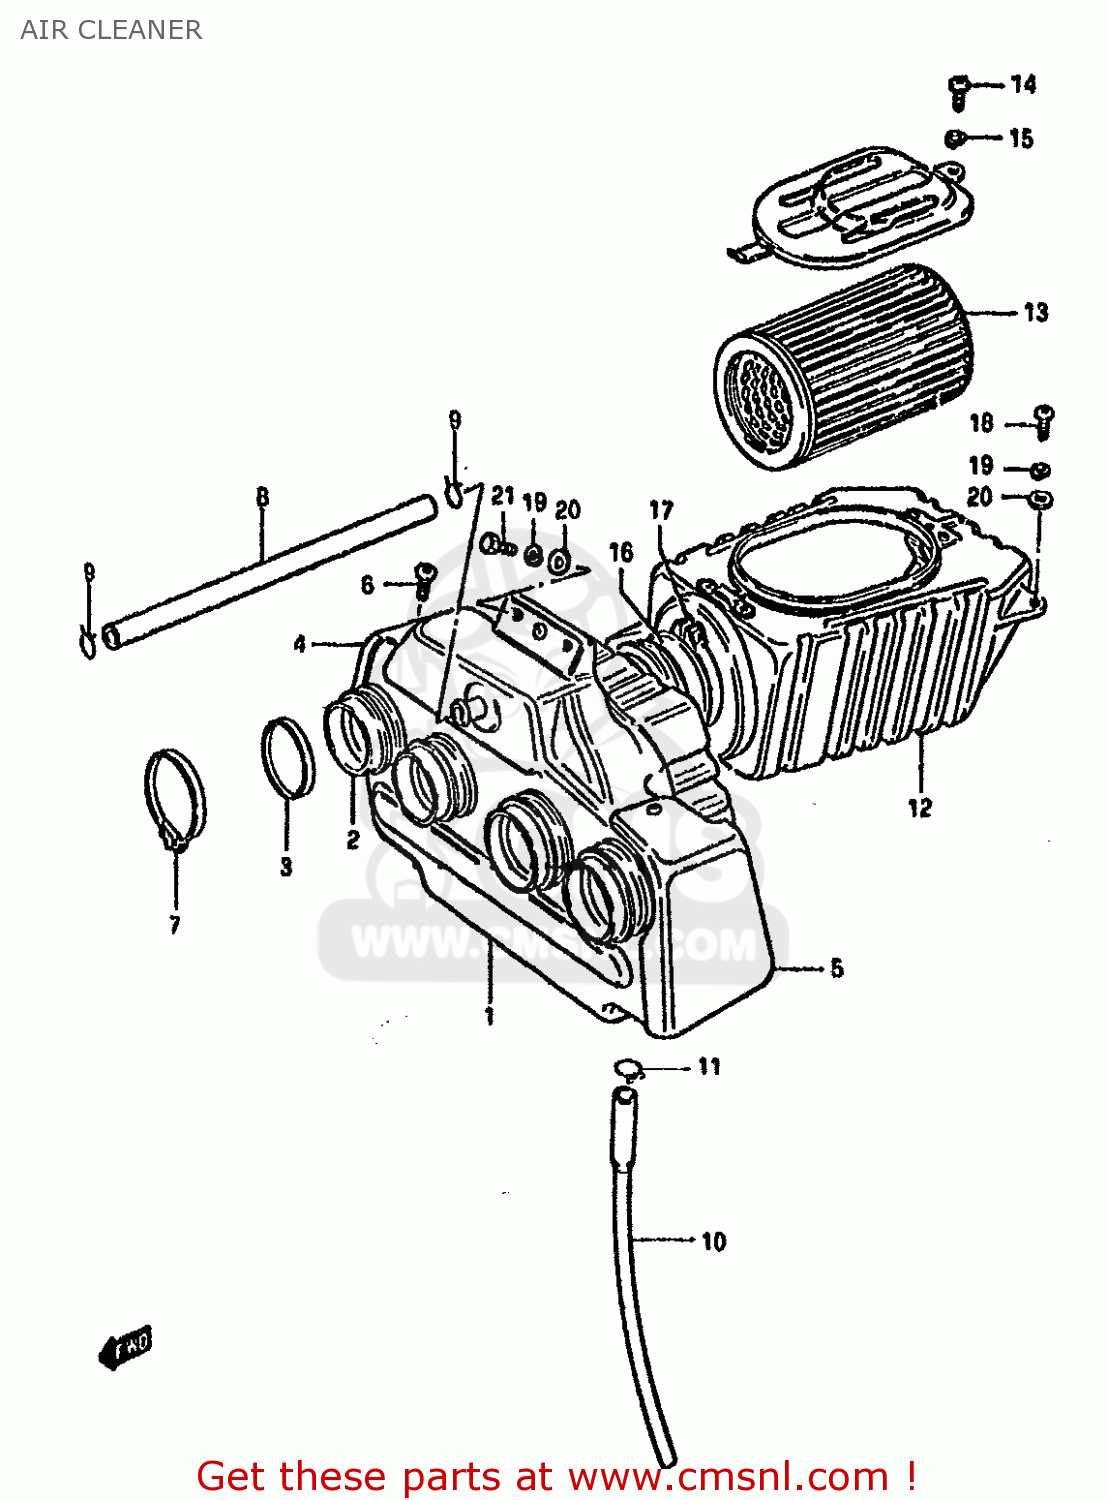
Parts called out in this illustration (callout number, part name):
1	CASE COMP,AIR CLEANER
2	TUBE,OUTLET
3	RING,CARBURETOR AIR INLET HOSE
4	COVER,AIR CLEA
5	COVER
6	.SCREW
7	CLAMP
8	TUBE,BREATHER
9	CLIP
10	HOSE,DRAIN
11	CLIP
12	CLEANER SET,AIR,REAR
13	FILTER,AIR CLEANER
14	SCREW
15	LOCK WASHER
16	HOSE,AIR CLEANER
17	BAND
18	SCREW
19	LOCK WASHER
20	WASHER 6MM
21	BOLT
